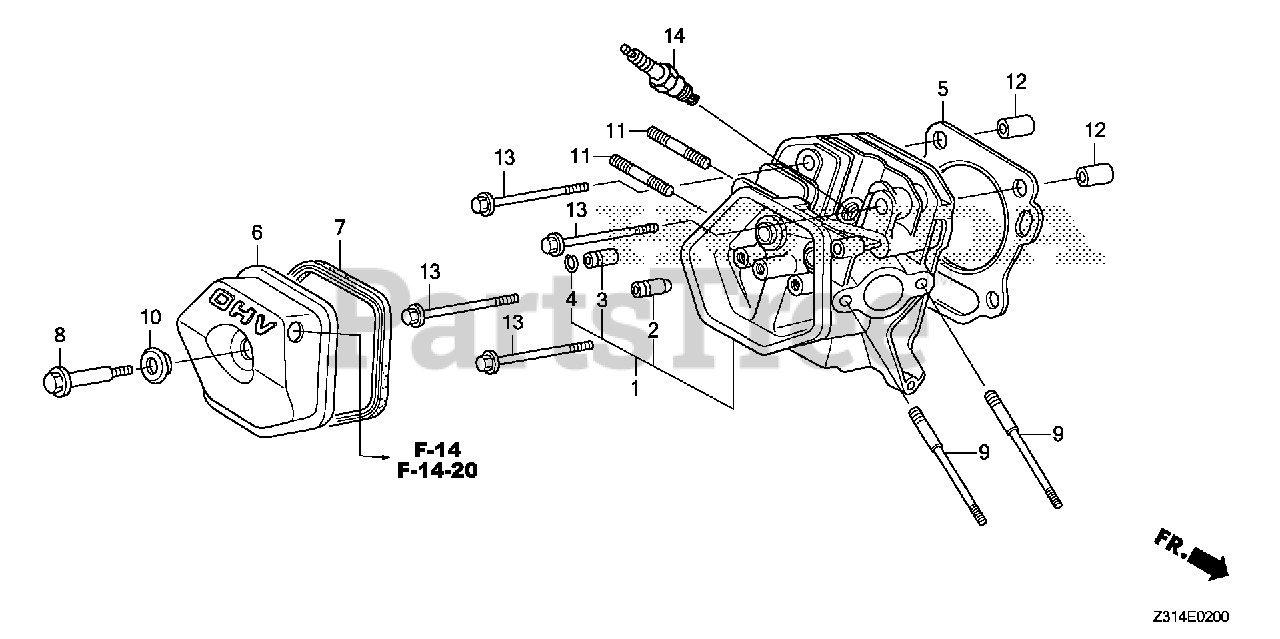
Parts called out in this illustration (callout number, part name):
1	CYLINDER HEAD
2	GUIDE, VALVE (OVER SIZE)
3	GUIDE, EX. VALVE (OVER SIZE)
4	CLIP, VALVE GUIDE
5	GASKET, CYLINDER HEAD (NIPPON LEAKLESS)
6	COVER, HEAD
7	GASKET, HEAD COVER
8	BOLT, HEAD COVER
9	BOLT, STUD (8X115)
10	WASHER, HEAD COVER
11	BOLT, STUD (8X32)
12	PIN, DOWEL (12X20)
13	BOLT, FLANGE (10X80)
14	SPARK PLUG (BPR5ES) (NGK)
